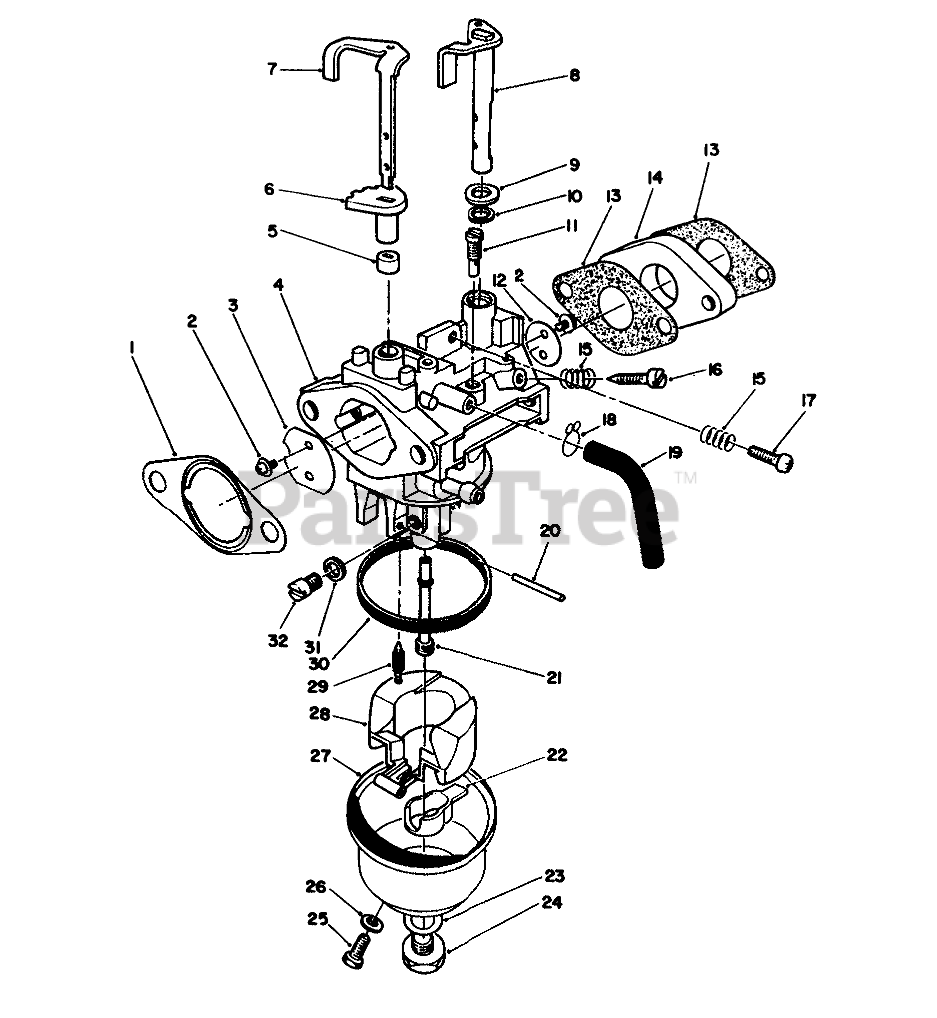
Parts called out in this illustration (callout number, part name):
1	GASKET F/W ENGINE
2	Screw
3	VALVE
4	Body-Carburetor
5	LOWER CHOKE RING
6	UPPER CHOKE RING
7	Shaft-Choke Valve
8	SHAFT
9	WASHER
10	Seal-Throttle Shaft
11	JET - PILOT
12	VALVE
13	GASKET INTAKE
14	INSULATOR - CARB.
15	SPRING-PILOT SCREW
16	ADJUSTER
17	SCREW
18	CLAMP
20	Pin
21	NOZZLE - MAIN
22	SPACER
23	GASKET
24	SCREW
25	SCREW
26	Gasket-Drain Screw
28	FLOAT
29	NEEDLE
30	FLOAT BOWL GASKET
31	SPACER
32	JET-HIGH ALTITUDE
